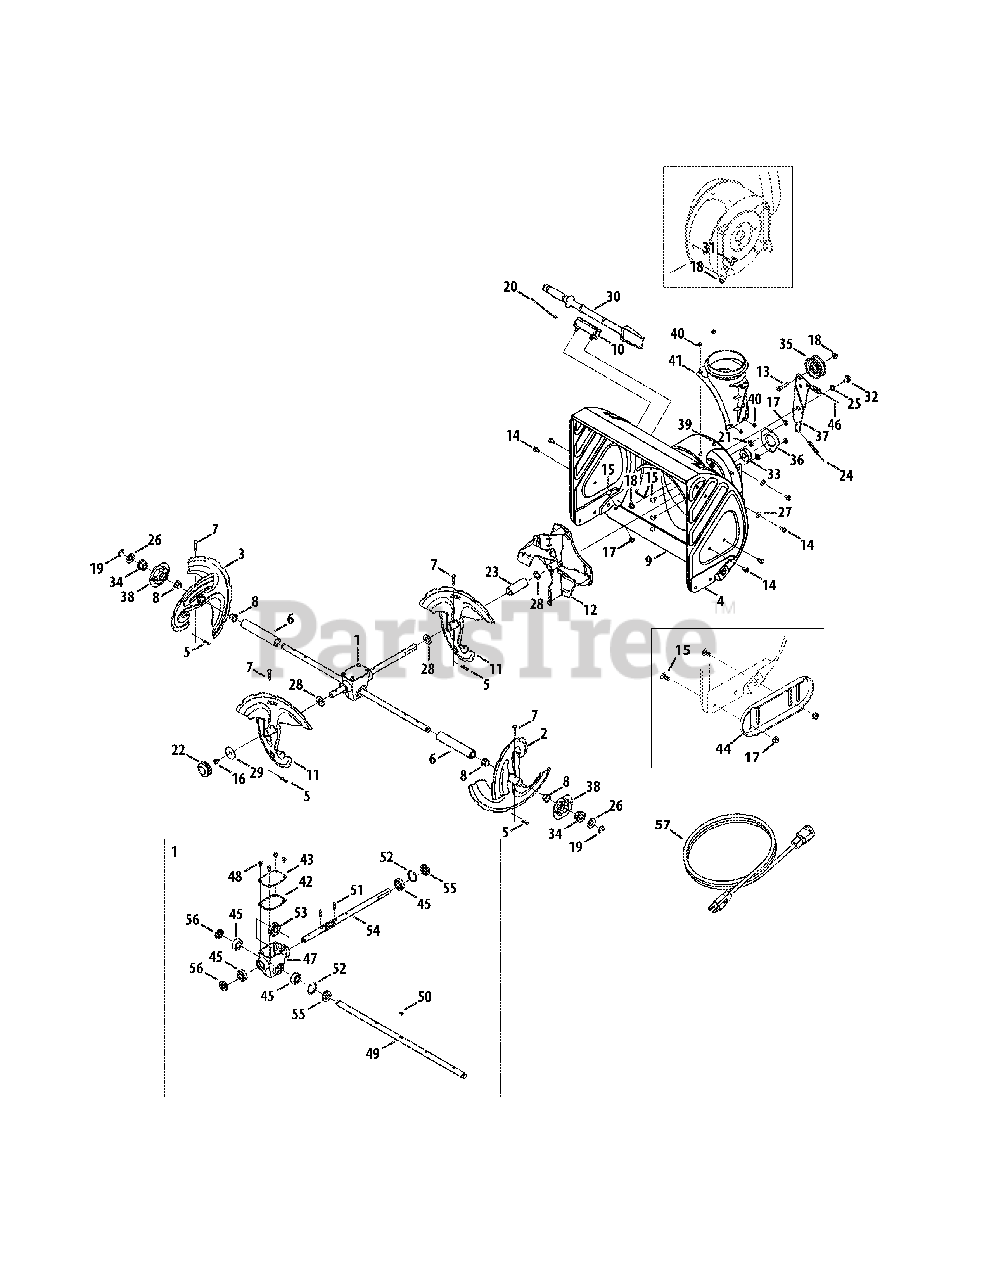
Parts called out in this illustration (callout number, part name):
1	Gearbox Assembly, Auger, 28"
2	Spiral Assembly - LH, 28"
3	Spiral Assembly - RH, 28"
5	Bow Tie Cotter Pin
6	Spacer, 1.25 OD x .75 ID x 7.805 (28")
7	Shear Pin
8	Flange Bushing, .800 x .910
9	Shave Plate, 28"
10	Clean-out Tool Mtg. Bracket
11	Accelerator Assembly
12	Impeller Assembly
13	Hex Bolt, 3/8-16 x 1.75
14	Screw, 5/16-18 x .750
15	Carriage Bolt, 5/16-18 x .750
16	Hex Washer Screw, 5/16-18 x .500
17	Flange Lock Nut, 5/16-18
18	Flange Lock Nut, 3/8-16
19	E-ring, .75
20	Cable Tie
21	Push-On Nut, .25 Dia.
23	Spacer, 1.35 OD x .76 ID x 2.755
24	Extension Spring, .38 OD x 4.59
25	Wave Washer, .625 x .885 x .0175
26	Flat Washer, .76 x 1.49 x .06
27	Bell Washer, .340 x .872 x .060
28	Flat Washer, .793 x 1.24 x .06
29	Flat Washer, .406 x 1.92 x .060
30	Clean-Out Tool
31	Shoulder Screw, 3/8-16 x .496 x .336
32	Shoulder Screw, 3/8-16 x .625 x .17
33	Flange Ball Bearing, .75 x 1.85
34	Hex Flange Bearing, .75 ID
35	Flat Idler Pulley
36	Bearing Housing
37	Auger Idler Bracket
38	Bearing Housing
39	Carriage Screw, 1/4-20 x 0.75
40	Flange Lock Nut, 1/4-20
41	Chute Adapter
42	Gearbox Gasket
43	Gearbox Cover
44	Slide Shoe Deluxe, Steel
44	Polymer Reversible Shoe Kit
45	Ball Bearing, .75 x 40 x 12
46	Auger Clutch Cable
47	Auger Housing
48	Screw, 1/4-20 x 0.75
49	Axle, Auger, 28"
50	Hi-Pro Key
51	Pin, Roll, .25 x 1.0
52	Retainer Ring
53	Worm Gear, 20T
54	Worm Shaft
55	Seal, .75 x 40mm x .25
56	Seal, .75 x 1.375 x .25
57	3-Prong Extension Cord
